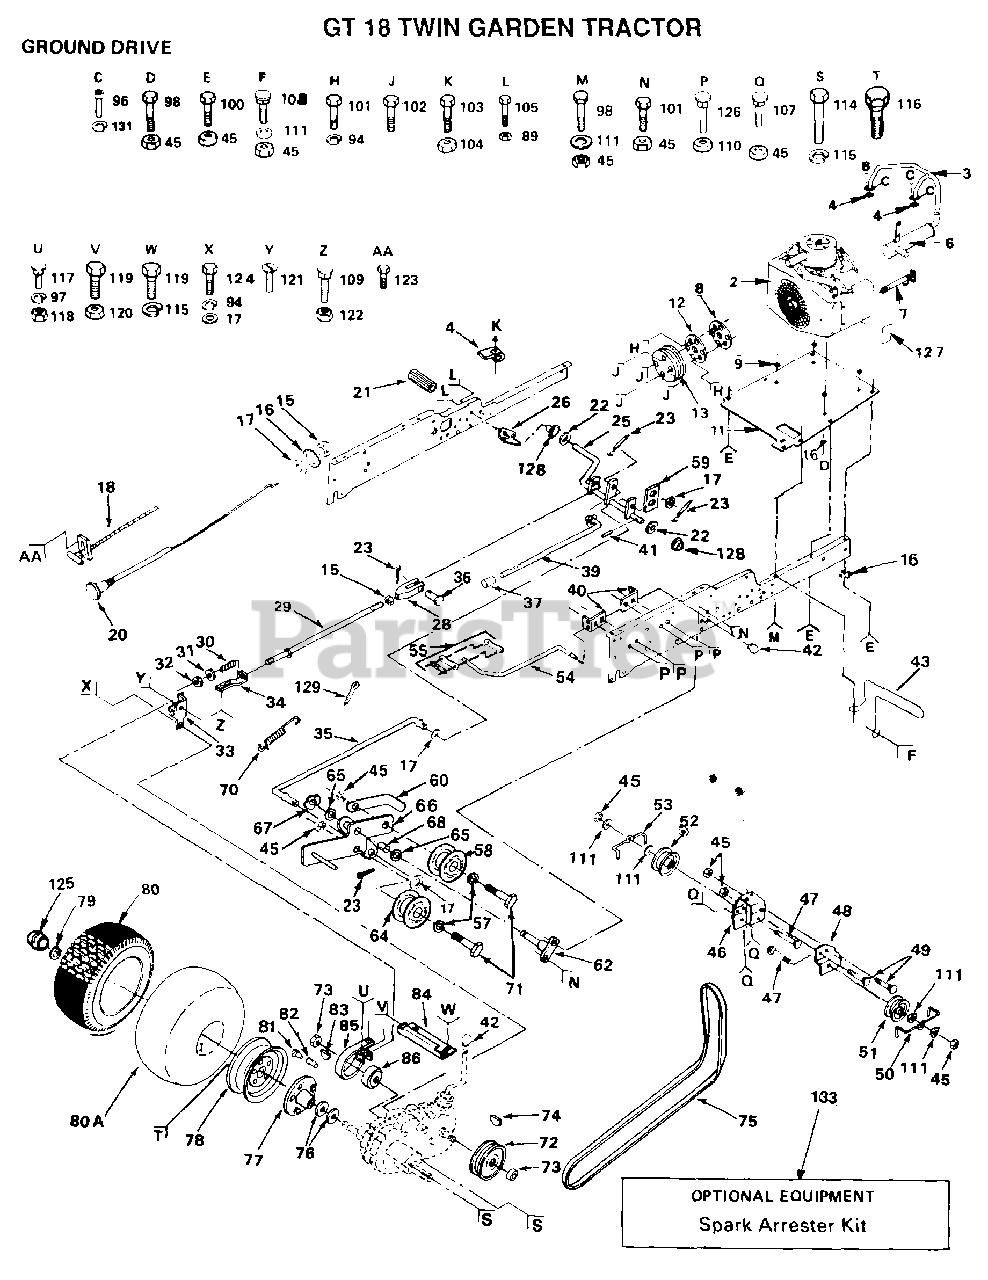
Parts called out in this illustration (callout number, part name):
2	ENGINE - 18 H.P. SPEC. #24573
3	EXHAUST TUBE T
7	DRAIN VALVE
8	CHAFF GUARD T
11	"ENG. T, BASE"
12	ADAPTER T
14	ACT-SWITCH T
16	LOCKWASHER
17	WASHER
21	PEDAL COVER T
22	WASHER
25	SHAFT ASSY GT
26	BRKT SWITCH GT
28	YOKE GTV
29	BRAKE ROD T
30	SPRING T
31	WASHER
33	BRAKE BRKT ASSY T
34	GUIDE ROD T
35	ROD CLUTCH GTV
36	CLEVIS PIN T
37	PLUNGER CAP T
40	ROD BRACKET GT
41	ROLL PIN STD
42	KNOB
43	GUARD MUFFLER HYT
47	BOLT
49	BOLT
50	BELT GUARD T
51	IDLER-FLAT T
52	PULLEY V IDLR GTV
53	BELT GUARD GT
54	ROD SHIFT HI LO
55	CONNECTING LINK
57	WASHER
59	RETAINER SPRING
60	RETAINER BELT
62	BRACKET ASSY GTV
65	WASHER T
66	BRACKET CLUTCH
67	KLIP RING
68	"LY, BEARING"
70	SPRING EXT CLUTCH
72	PULLEY GT
73	NUT STD
75	BELT-V.98.5.GD.DV
76	WASHER T
79	KLIP RING
80A	TUBE.23X8/10-12
81	VALVE CAP
82	VALVE STEM LT
86	BRAKE DRUM T
94	LOCKWASHER
96	SCREW
97	LOCKWASHER
101	BOLT
102	SCREW
103	SCREW
105	BOLT LT
107	BOLT
108	BOLT.3/8-14X1.25
111	WASHER GT
114	BOLT
115	LOCKWASHER
117	BOLT T
119	BOLT
120	NUT GTV
121	SCREW
123	SCREW
125	CAP-HUB GT
126	BOLT
128	NYLINER T
129	COTTER PIN
